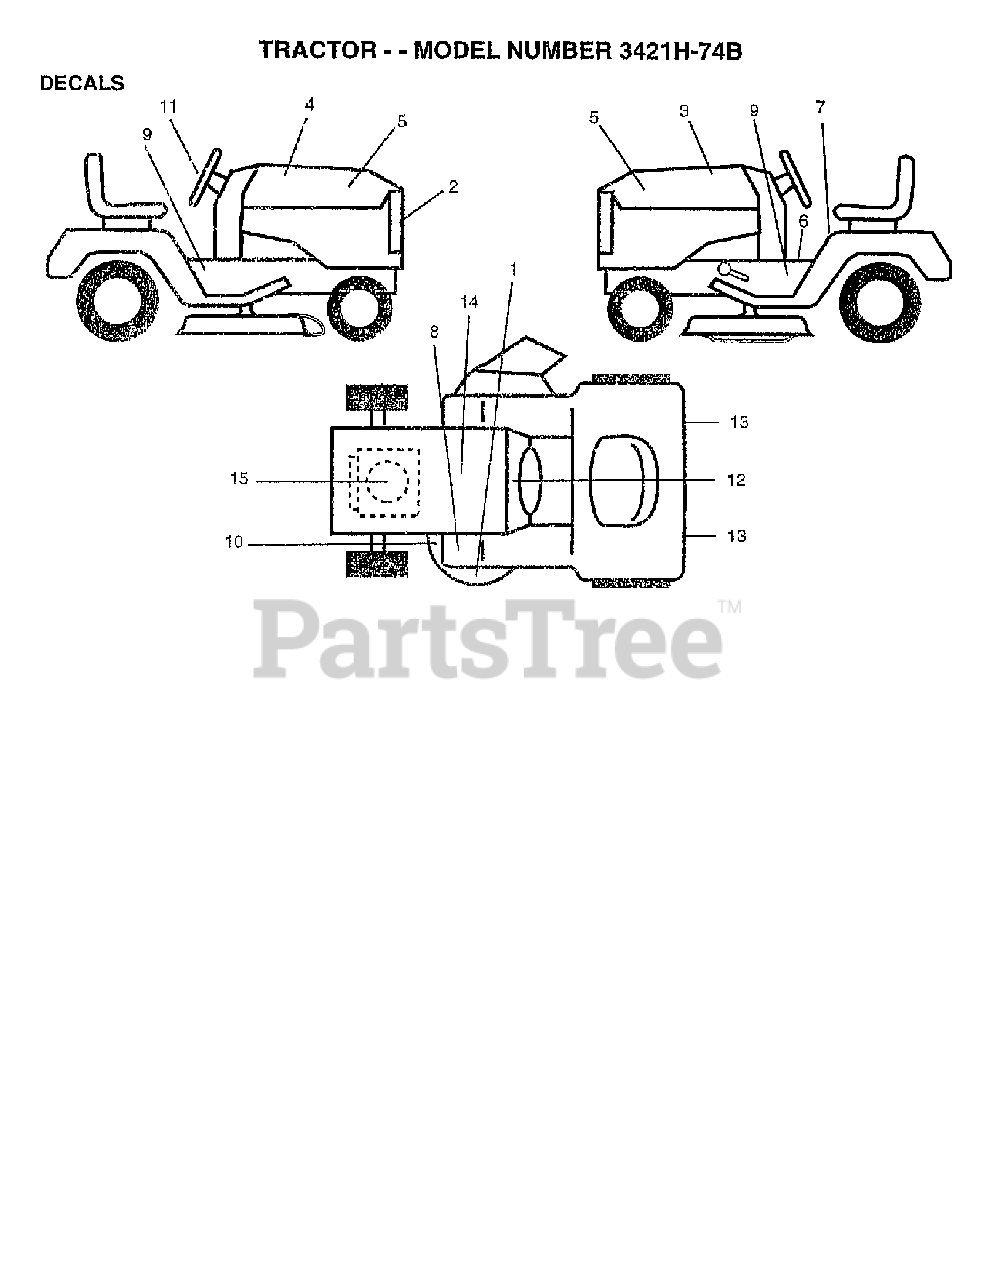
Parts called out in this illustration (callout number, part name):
2	Poulan TBD
3	Poulan TBD
4	Poulan TBD
5	Poulan TBD
6	DECAL PARK BRAKE
9	Poulan TBD
10	DECAL V-BELT SCHEMATIC
11	Poulan TBD
13	REFLECTOR-TAIL YT
14	DECAL BTRY SYMBOLS
15	Poulan TBD
